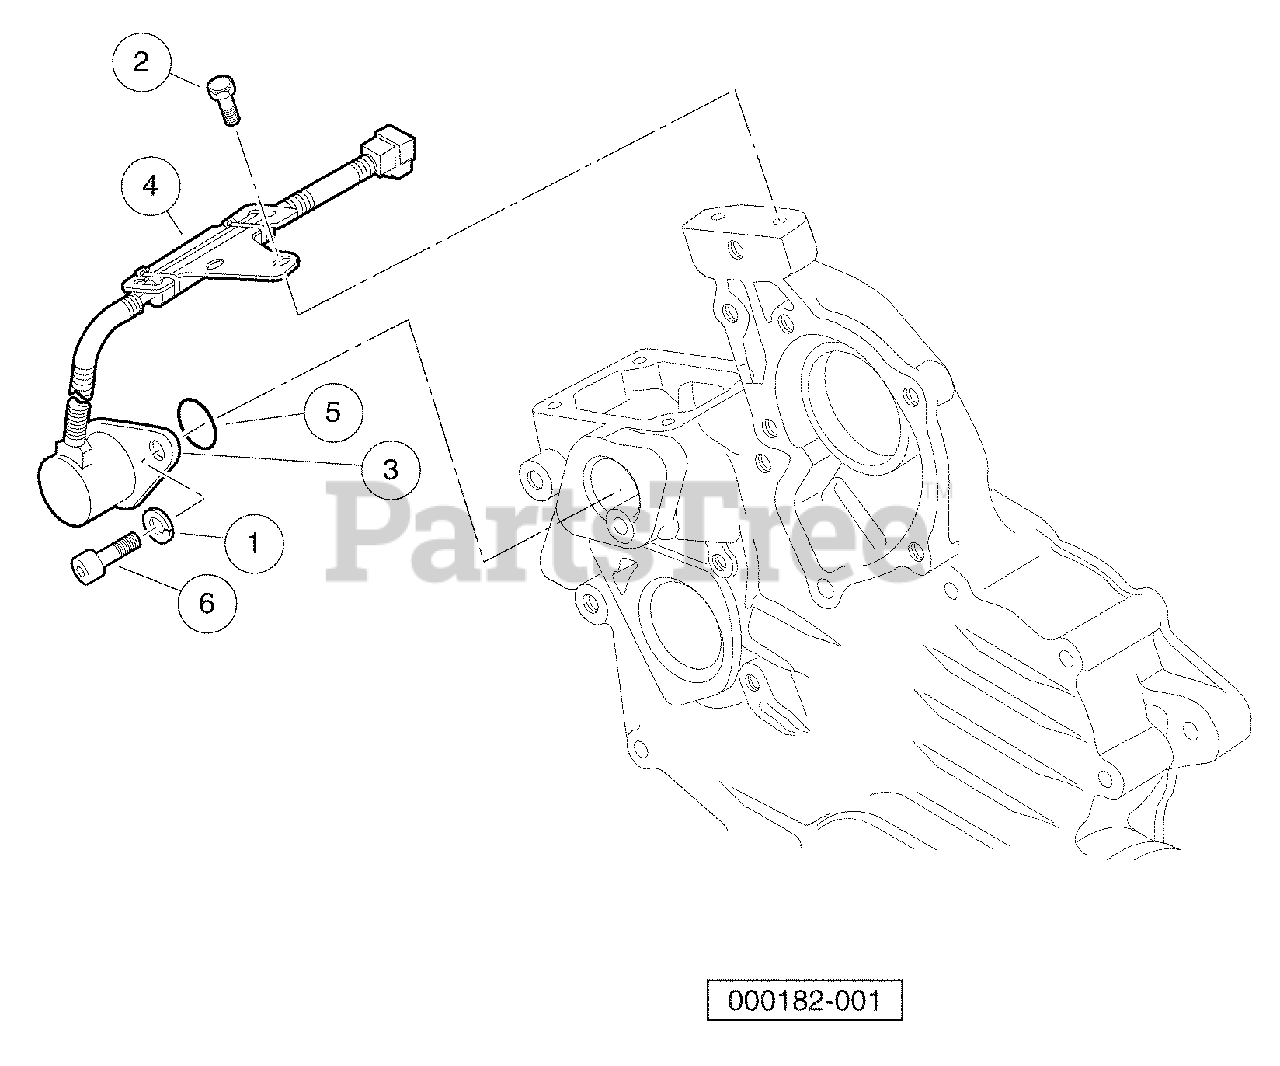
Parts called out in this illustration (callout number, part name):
1	Washer, Spring, M6, D722
2	Bolt, Solenoid, Stop, D722
3	Solenoid, Stop
4	Stay, Stop Solenoid
5	O-Ring, Stop Solenoid
6	Bolt, Stop Solenoid
